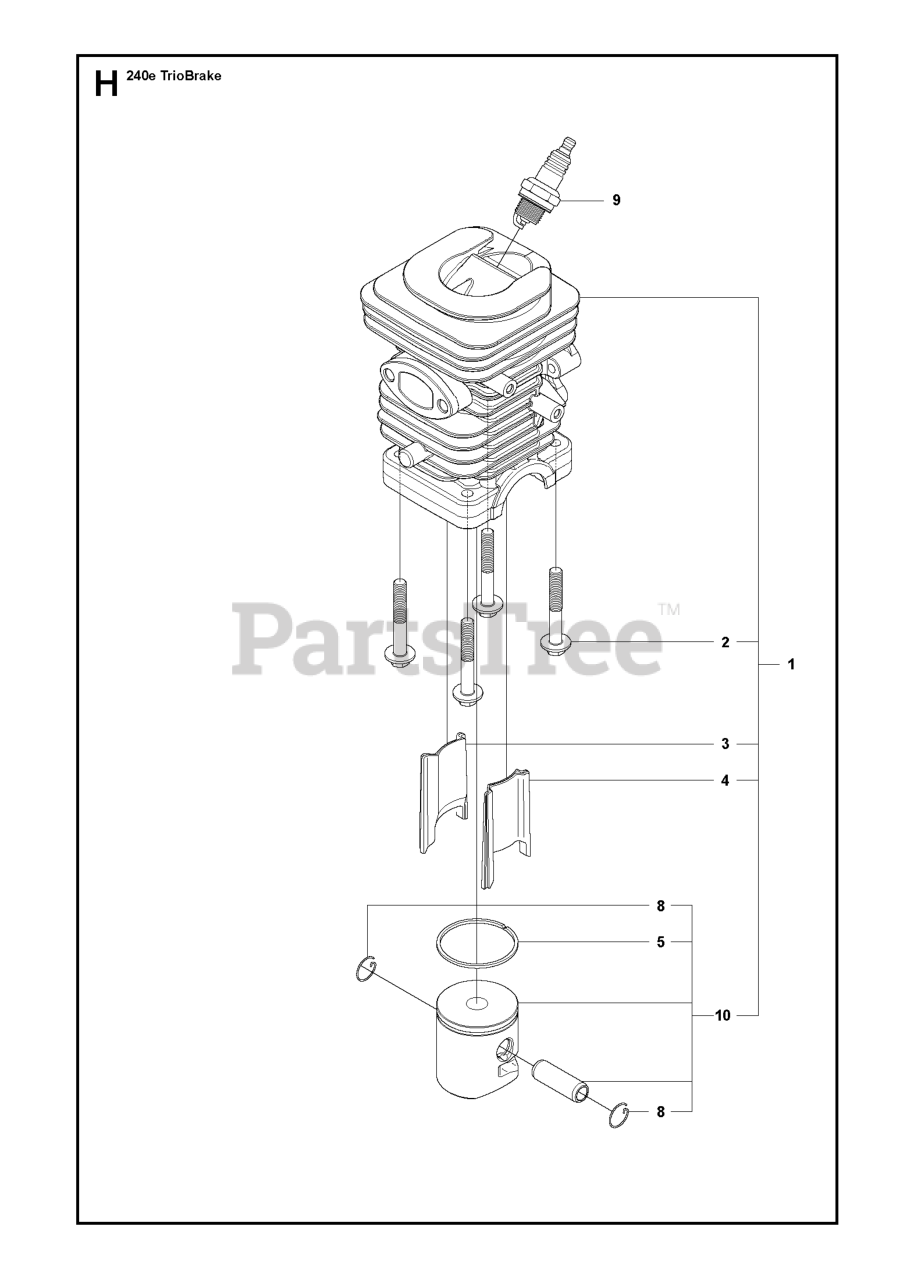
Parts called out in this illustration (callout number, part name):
1	KIT, CYLINDER & PISTON
3	CYLINDER INSERT LEFT 38CC
4	CYLINDER INSERT RIGHT 38CC
5	PISTON RING
8	C-CLIP,PSTN PIN 36/41
9	SPARK PLUG RCJ7Y
10	PISTON KIT
